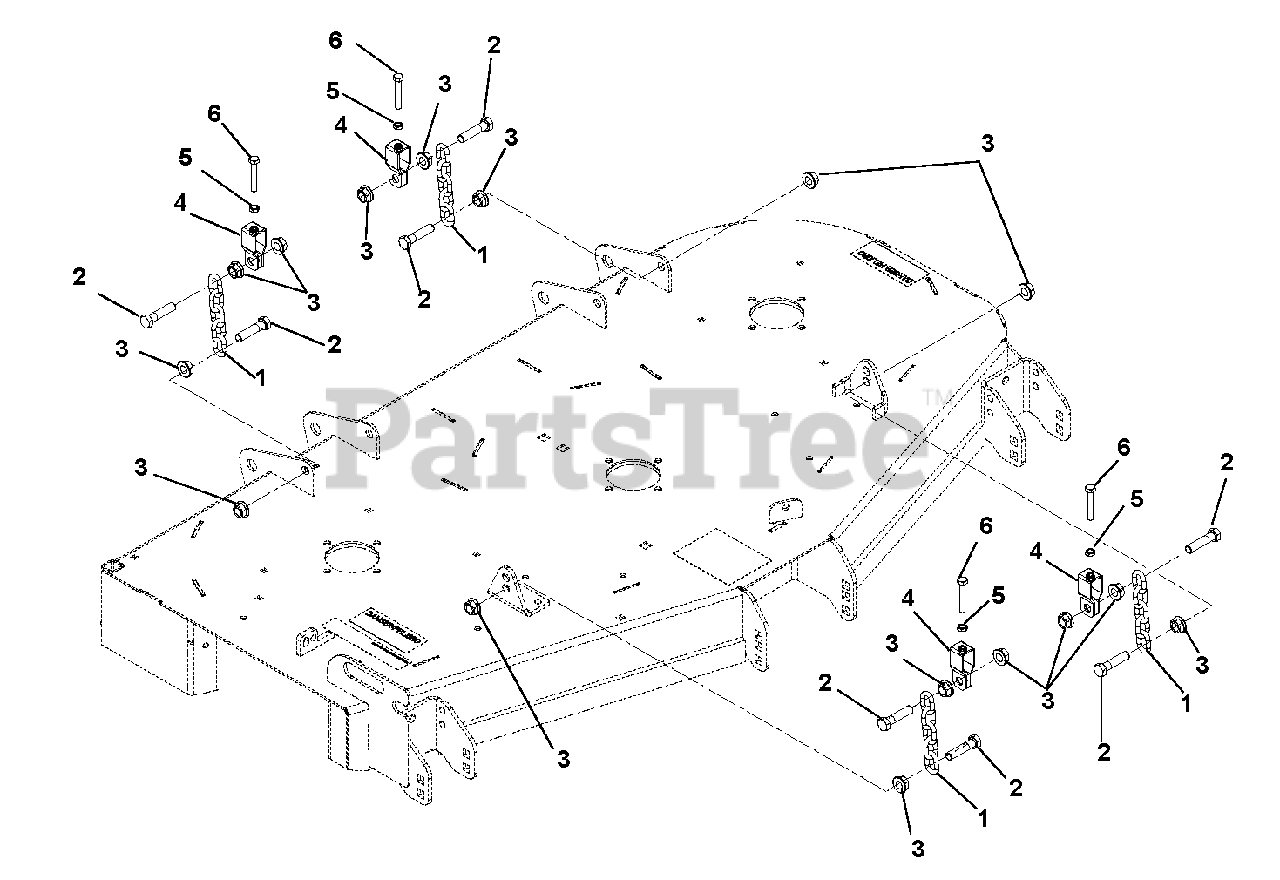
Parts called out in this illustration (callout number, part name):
1	Chain, Link
2	Bolt, Hex M12-1.75 x 50 Class 8.8
3	Nut, Spin Lock, Flange M12-1.75
4	Bracket, Deck Leveling
5	Nut, Jam .312-18
6	Bolt, Hex .312-18 x 2.00 FTH Grade 5
